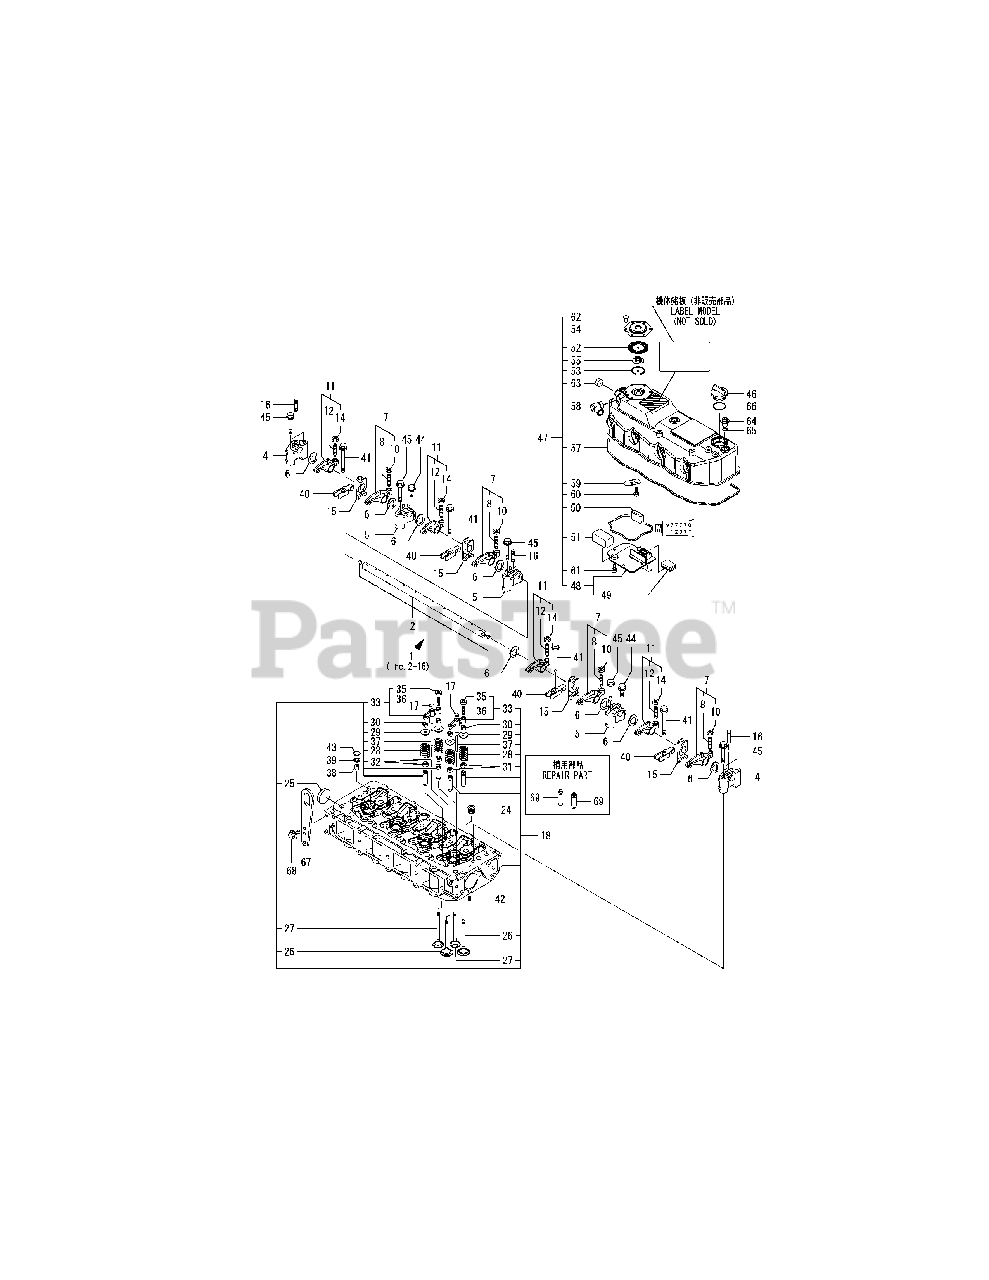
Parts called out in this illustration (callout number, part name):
1	SHAFT ASSY, ROCKER
2	SHAFT, ROCKER ARM
4	SUPPORT, ARM A
5	SUPPORT, ARM B
7	ARM KIT, ROCKER
8	SCREW, VALVE ADJUST
11	ARM KIT, ROCKER
12	SCREW, VALVE ADJUST
15	PEDESTAL, RETAINER
16	STUD M 8X 35 PLATED
17	SEAT, VALVE BRIDGE
18	HEAD ASSY, CYLINDER
24	PLUG PT1/4,SCREW
27	VALVE, EXHAUST
29	RETAINER, SPRING
31	SEAL, VALVE STEM
32	SEAL, VALVE STEM
33	BRIDGE ASSY, VALVE
36	ADJUSTER, BRIDGE
37	GUIDE, VALVE BRIDGE
38	PROTECTOR, NOZZLE
40	RETAINER, NOZZLE
42	SPRING PIN 6X12
43	O-RING 1A P-12.0
44	BOLT M 8X 25 PLATED
45	BOLT M 8X 50 PLATED
49	BAFFLE, BREATHER
50	BAFFLE, BREATHER
51	BAFFLE, BREATHER
54	PLATE, BREATHER
55	SPRING, DIAPHRAGM
57	GASKET, BONNET
58	ELBOW, BREATHER
65	O-RING 1A P-12.0
66	O-RING 1A P-32.0
67	LIFTER, ENGINE
68	BOLT M 8X 16 PLATED
